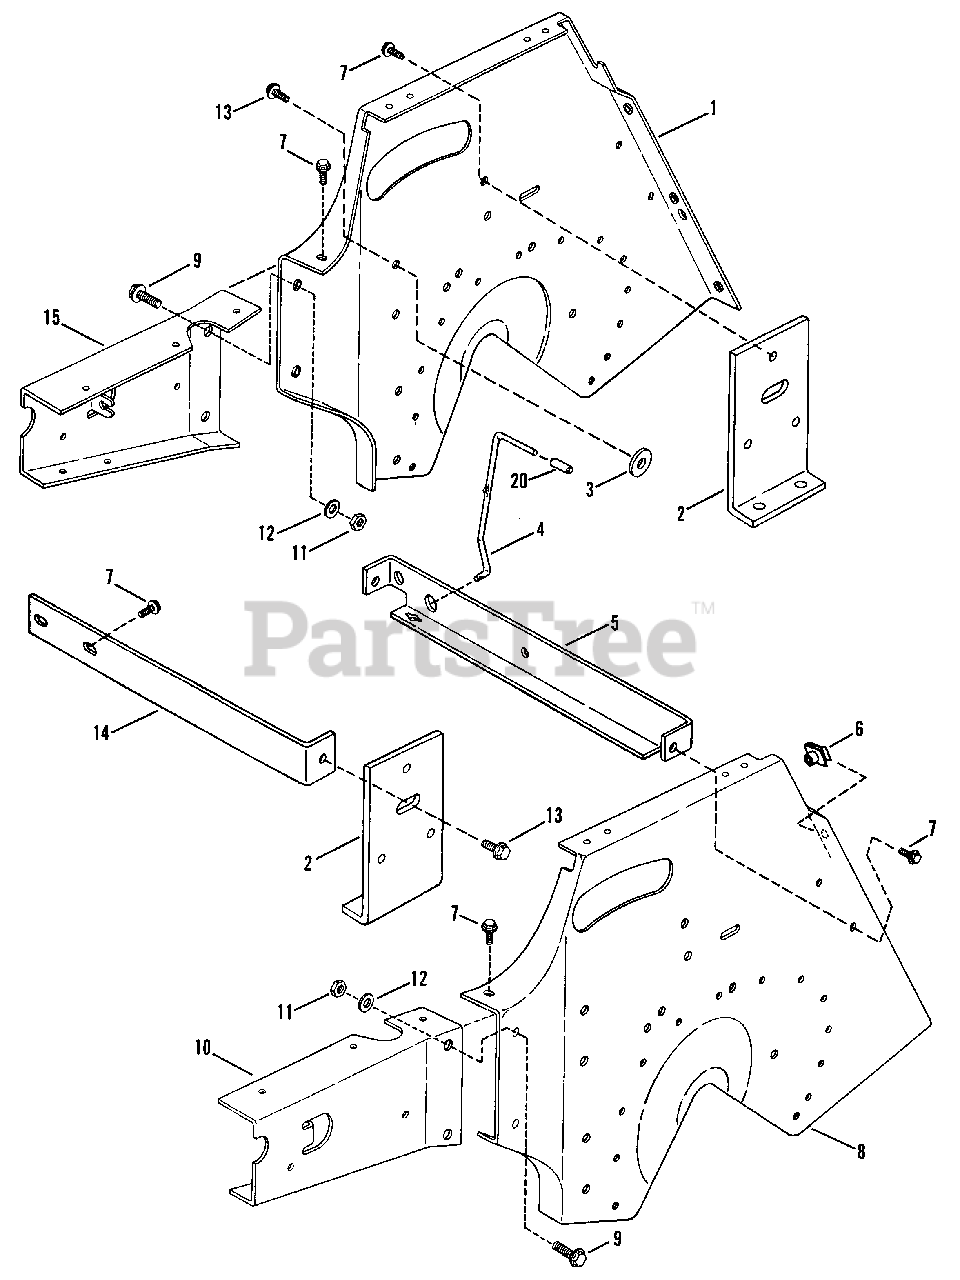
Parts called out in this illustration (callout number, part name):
1	TRANSMISSION SUPPORT, R.H. (No longer available)
2	BRACKET, Transmission Mount (No longer available)
3	WASHER .406 x 1.38 x .25
4	ROD, Release
5	BRACE, Torque
6	NUT, 5/16 Push-On
7	SCREW, 5/16-18x5/8" Self-Tapping
8	TRANSMISSION SUPPORT, L.H. (No longer available)
9	BOLT, 3/8-16x1" Hex Flange Lock
10	EXTENSION, Transmission Support, L.H. (No longer available)
11	NUT, 3/8-16 Center Lock
12	WASHER, 3/8 SAE
13	SCREW, 5/16-18x3/4" Self-Tapping
14	BRACE, Shift Bracket (No longer available)
15	EXTENSION, Transmission Support, R.H. (No longer available)
20	CAP, Release Rod
